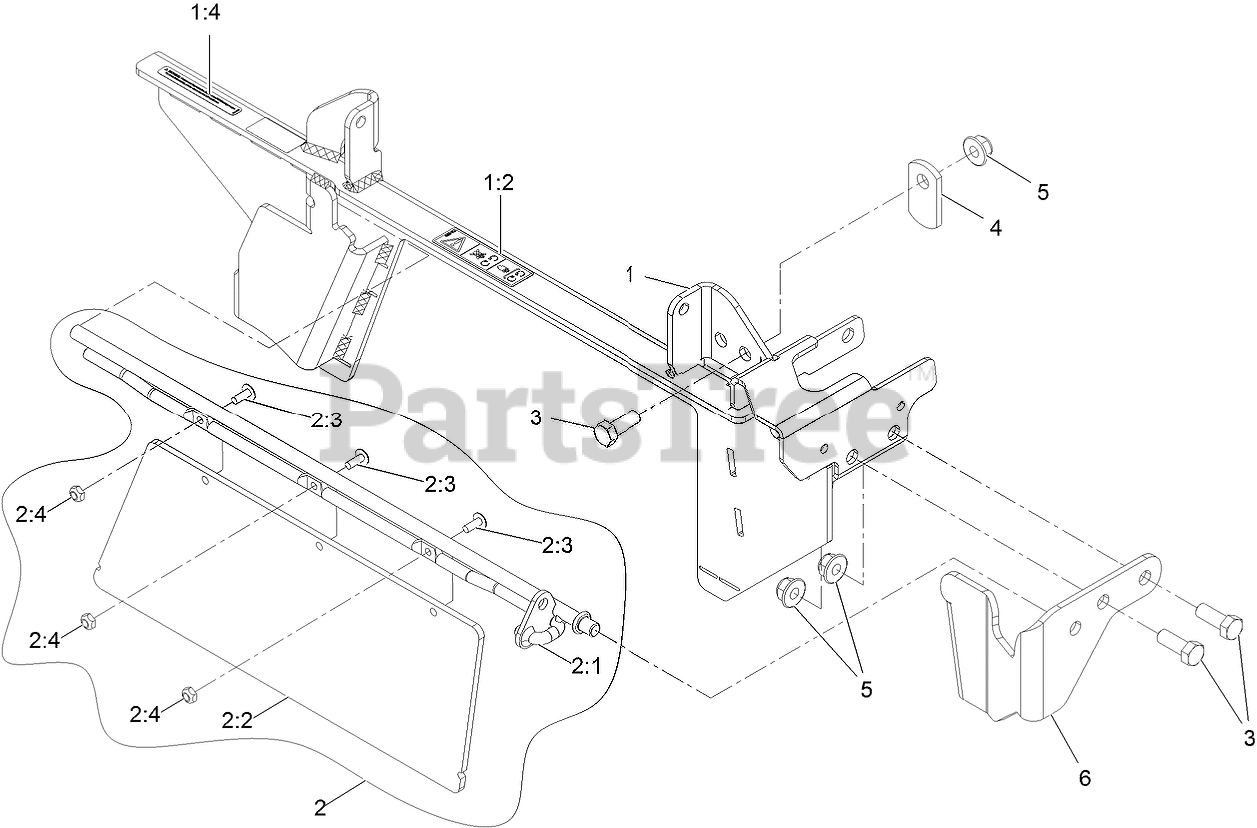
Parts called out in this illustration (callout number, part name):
1	OCD FRAME ASM W/ DECALS
1:2	DECAL, COVER MISSING
1:4	DECAL-WARNING
2	Ocd Gate ASM
2:1	Gate Pivot ASM
2:2	GATE-OCD
2:3	SCREW-PTH
2:4	NUT-LOCK, NI
3	SCREW-HH
4	LATCH-CATCHER, GRASS
5	NUT-HF, NI
6	Brkt,Chute Front
